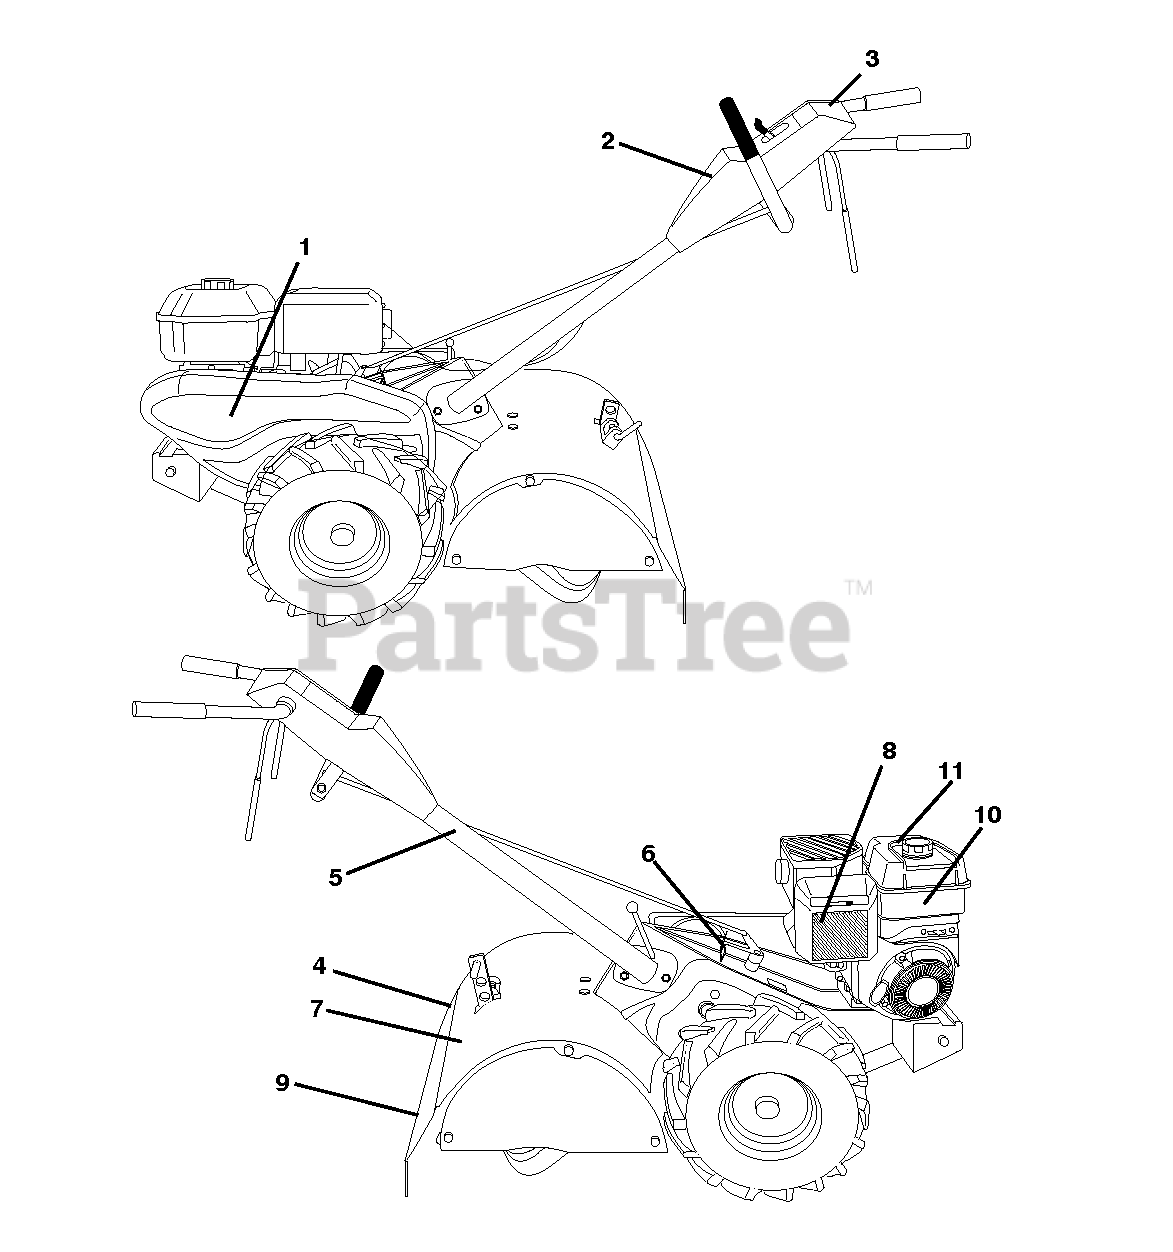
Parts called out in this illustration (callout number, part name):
1	RP.DECAL.BADGE.170MM.TEXTLOGO
2	DECAL, HUSQVARNA,CONTROL PANEL
3	RP.DECAL.BADGE.170MM.TEXTLOGO
4	DECAL.SHIELD
6	DECAL TI (2 2)
7	DECAL.SHIFT.INDICATOR.TILLER
9	DECAL TI
11	DECAL.WARNING.SHLD.ENG/FR
